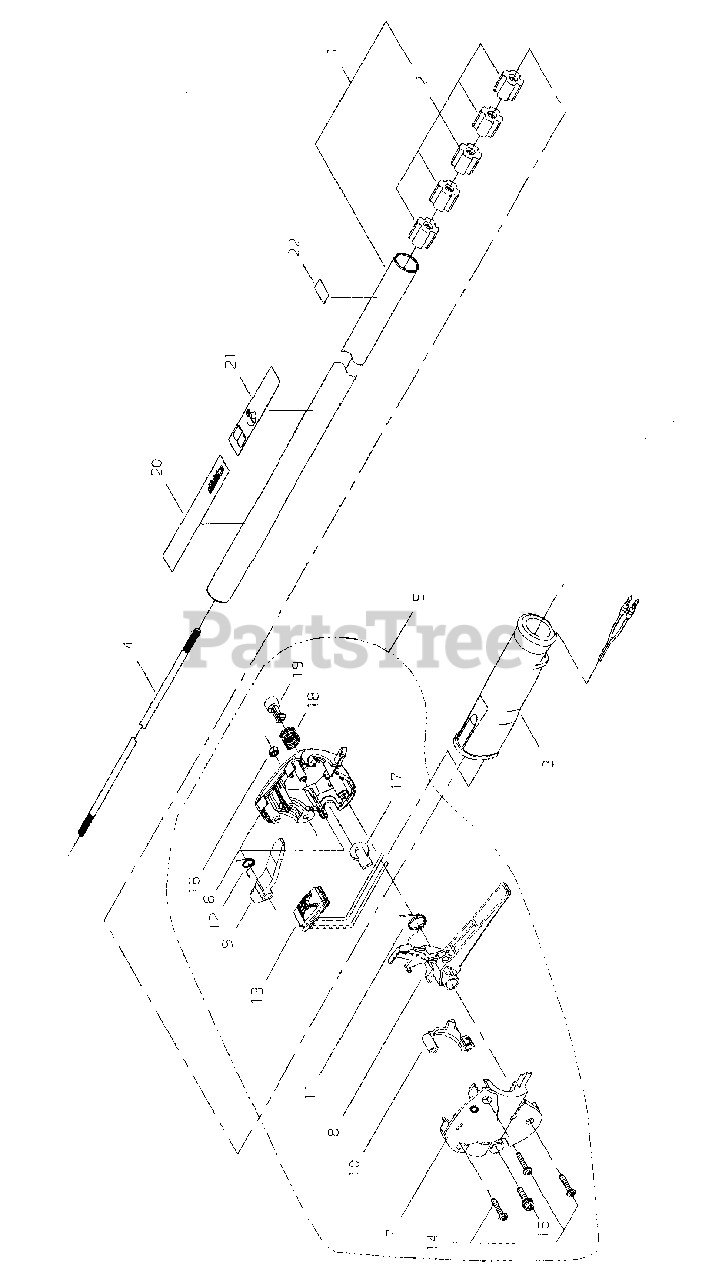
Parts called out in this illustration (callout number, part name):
1	MAIN PIPE ASSY
2	BUSHING
3	GRIP - REAR
4	DRIVESHAFT - SOLID
5	THROTTLE CONTROL ASSY
6	HANDLE, CONTROL - RIGHT
7	HANDLE, CONTROL - LEFT
8	TRIGGER, THROTTLE
9	LEVER, TRIGGER LOCKOUT
10	LOCKOUT, THROTTLE
11	SPRING, TRIGGER
12	SPRING, LOCKOUT LEVER
13	SWITCH, IGNITION
14	SCREW - 4X20 -- TAPPING
15	SCREW - 5X20
16	NUT - 5
17	PLUG
18	SPRING
19	LOCK, THROTTLE
20	LABEL - SHINDAIWA PROFESSIONAL
21	LABEL - CAUTION
22	LABEL - HANDLE LOCATION
23	HANGER
24	SCREW - 5X12
